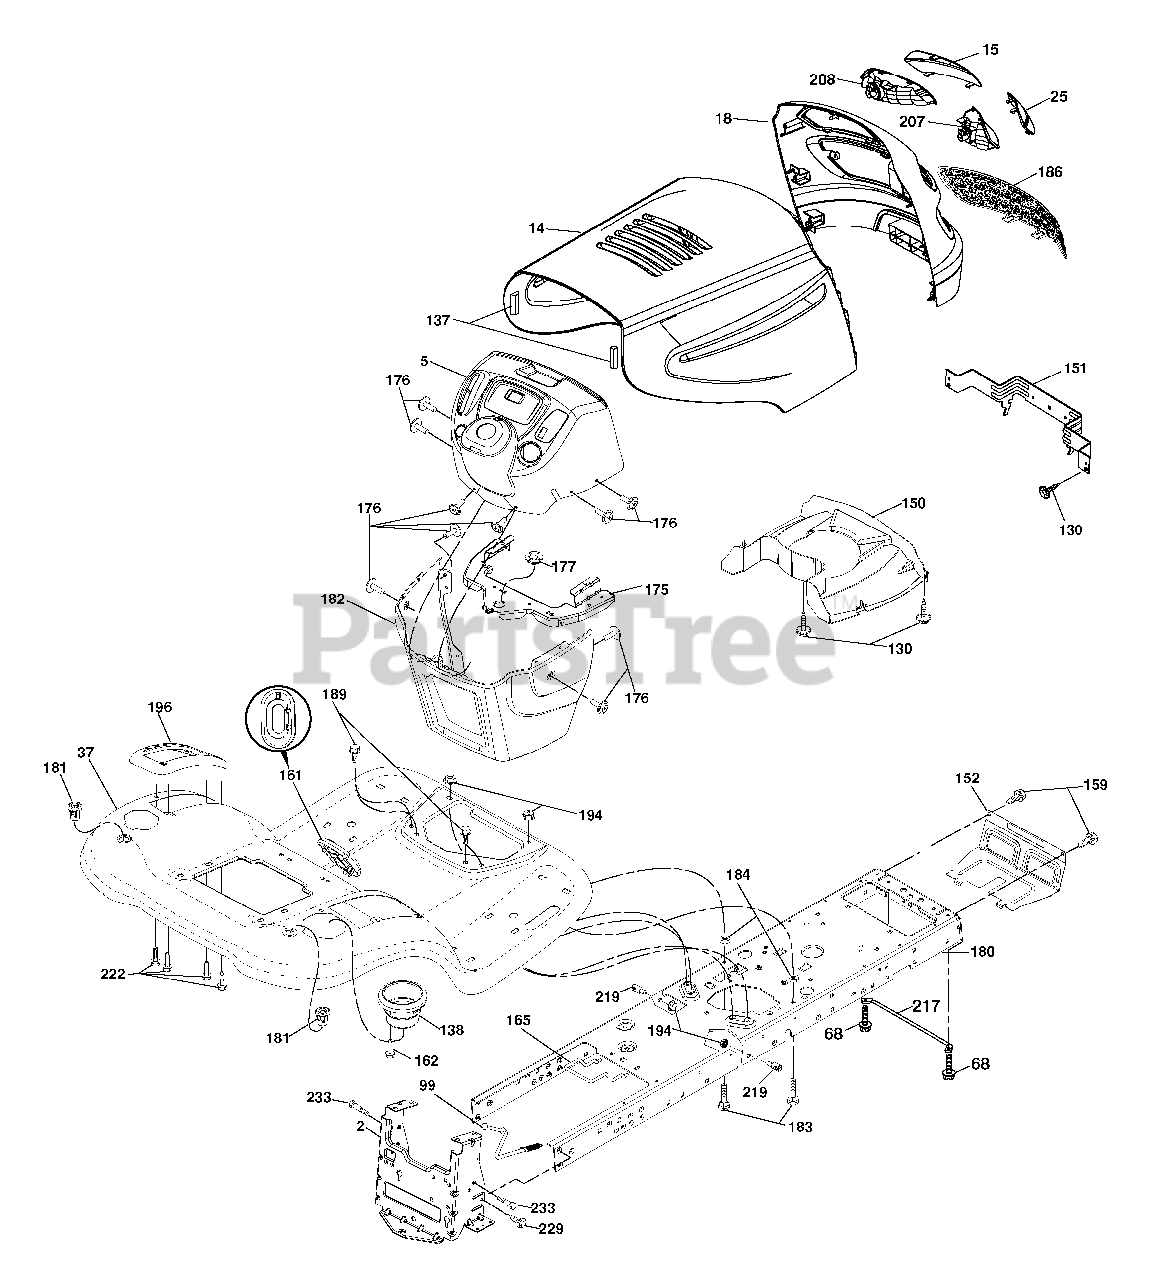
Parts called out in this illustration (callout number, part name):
2	Drawbar
5	Dash
14	Hood
15	Lens Grille LH
18	Grille
25	Lens Grille RH
37	Fender
68	Screw 5/16-18 x 1/2
99	Rod Asm Bypass
130	Screw 10 x 3/4 Single Lead-Hex
137	Bumper Hood
138	Cupholder
150	Duct Heat Hood
151	Bracket Pivot
152	Shield Browning/Debris
159	Screw Hexwsh Thdrol 3/8-16 x 3/4
161	Window Fuel
162	Screw Hex Wsh Hi-Lo 1/4 x 1/2 UNC
165	Bracket Support Tank
175	Crossmember
176	Screw 10-24 x 5/8 Wshd Qdrx
177	Bushing Steering
181	Bushing Mtg. Fender Crgo.
182	Dash Lower
183	Bolt Fin Hex 5/16-18 x 1-1/4
184	Spacer Fender
189	Screw 5/16-18 x 3/4
194	Nut Lock Hex Flange 5/16-18
196	Console Asm. Deck Lift
207	Bezel RH
208	Bezel LH
217	Rod Pivot Chassis/Hood
219	Stud Fastener
222	Screw thd Roll 1/4-20 x 5/8
229	Screw 3/8-16 x 1
233	Bolt Shoulder
